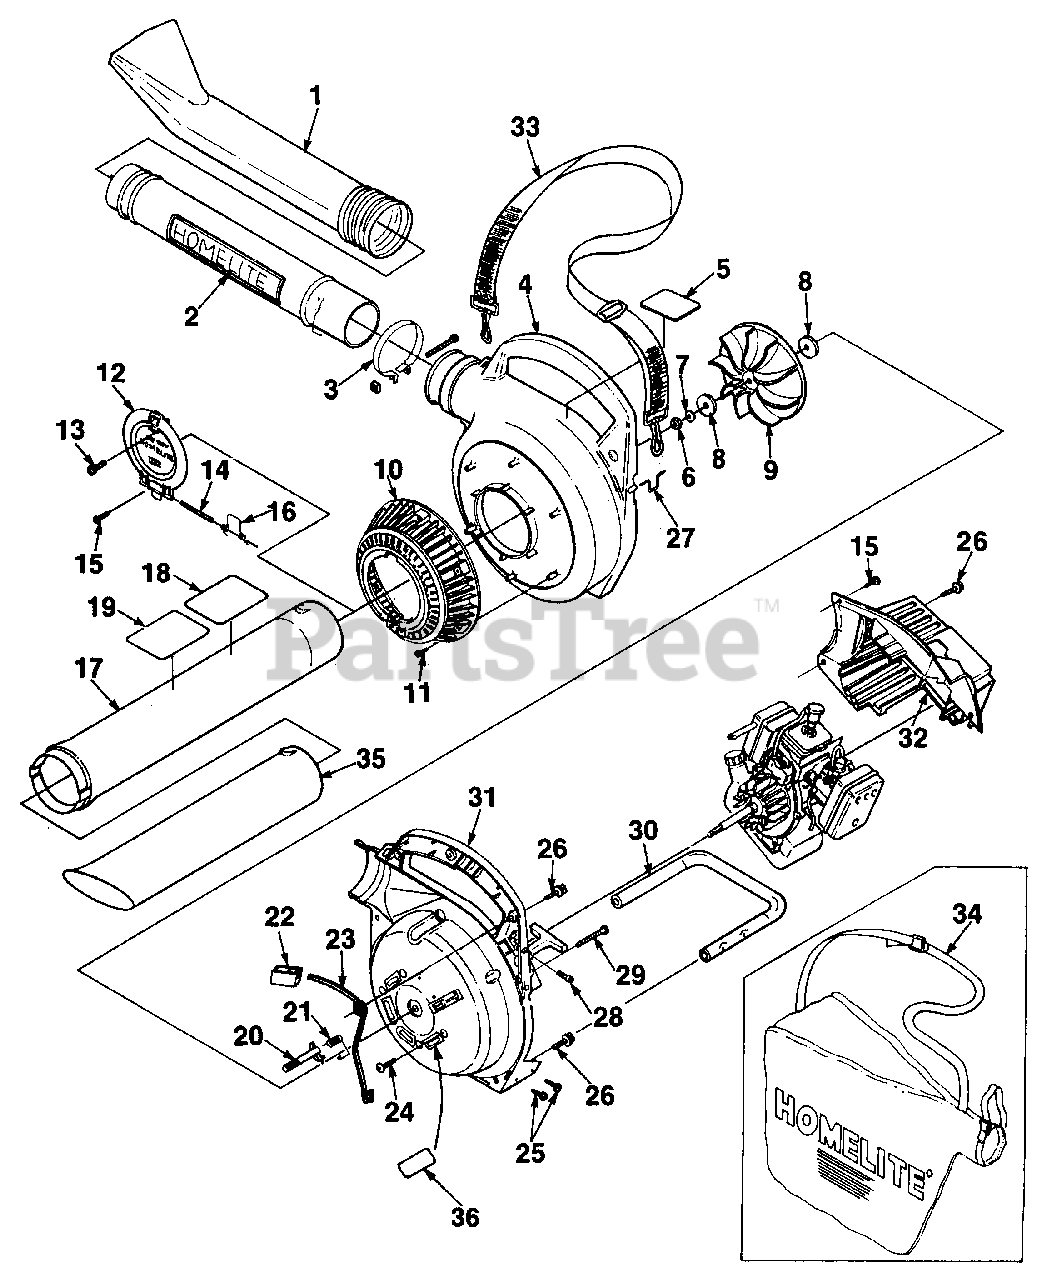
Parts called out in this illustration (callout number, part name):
1	NOZZLE - Sweeper
2	TUBE w/DECAL
3	CLAMP
4	HOUSING - Volute (outer)
5	DECAL - Warning
6	NUT - Hex 5/16-24
7	WASHER - Belleville #10
8	WASHER - Fan
9	FAN - Blower
10	GRILLE - Blower Vac
11	SCREW - Thd forming (#6-19 x 3/4)
12	COVER - Access
13	SCREW - Thd Rolling #10 x 5/8
14	PIN - Cover hinge
15	SCREW - Thd forming #8 x 1/2
16	SPRING - Access Cover
17	TUBE w/DECAL (Inner) 180V Only
18	DECAL (180V Only)
19	DECAL - Warning 180V Only
20	LATCH - Throttle
21	SPRING - Throttle latch
22	TRIGGER - Throttle
23	LEVER - Throttle
24	SCREW - Thd Forming
25	SCREW - Tapping pan #8 x 1/2
26	SCREW - Thd forming #10 x 3/4
27	LOOP - Wire
28	SCREW - Fil. hd. #8-32 x 5/8
29	SCREW - Hex hd. #10 x 1 5/8
30	HANDLE - Lower (180V Only)
31	HOUSING - Volute (inner)
32	SHROUD
33	STRAP - Shoulder
34	BAG - Leaf (180V Only)
35	TUBE - (outer) 180V Only
36	KIT - Sealing
